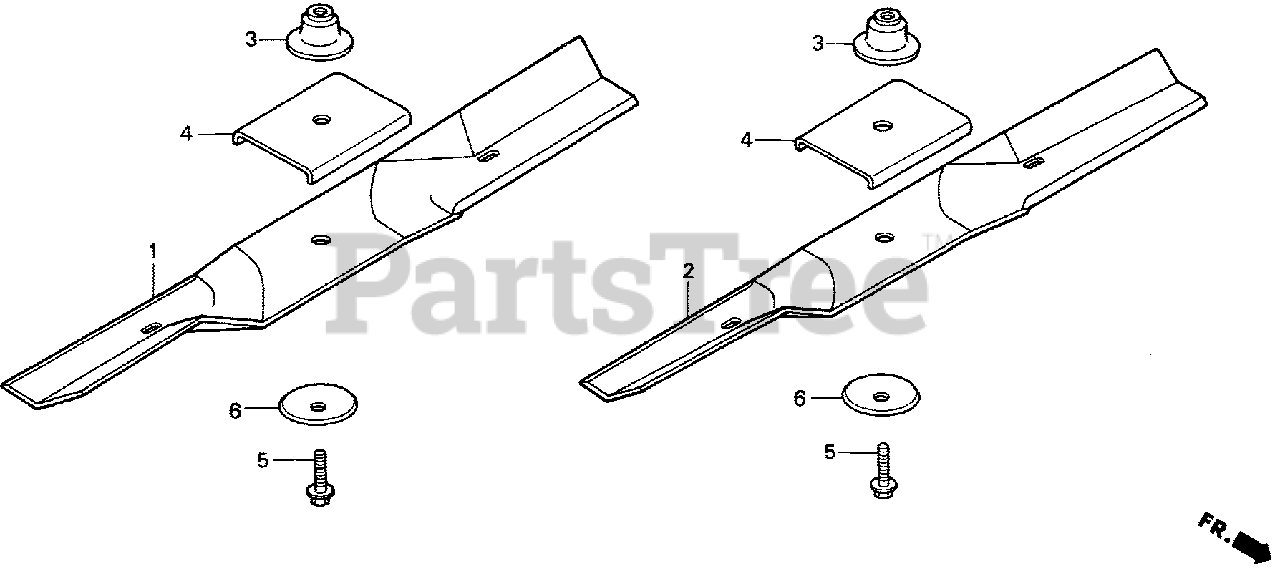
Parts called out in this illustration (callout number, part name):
1	BLADE, R. ROTARY
2	BLADE, L. ROTARY
3	HOLDER, BLADE
4	HOLDER, BLADE (B)
5	BOLT, BLADE HOLDER (10X28)
6	WASHER, BLADE
